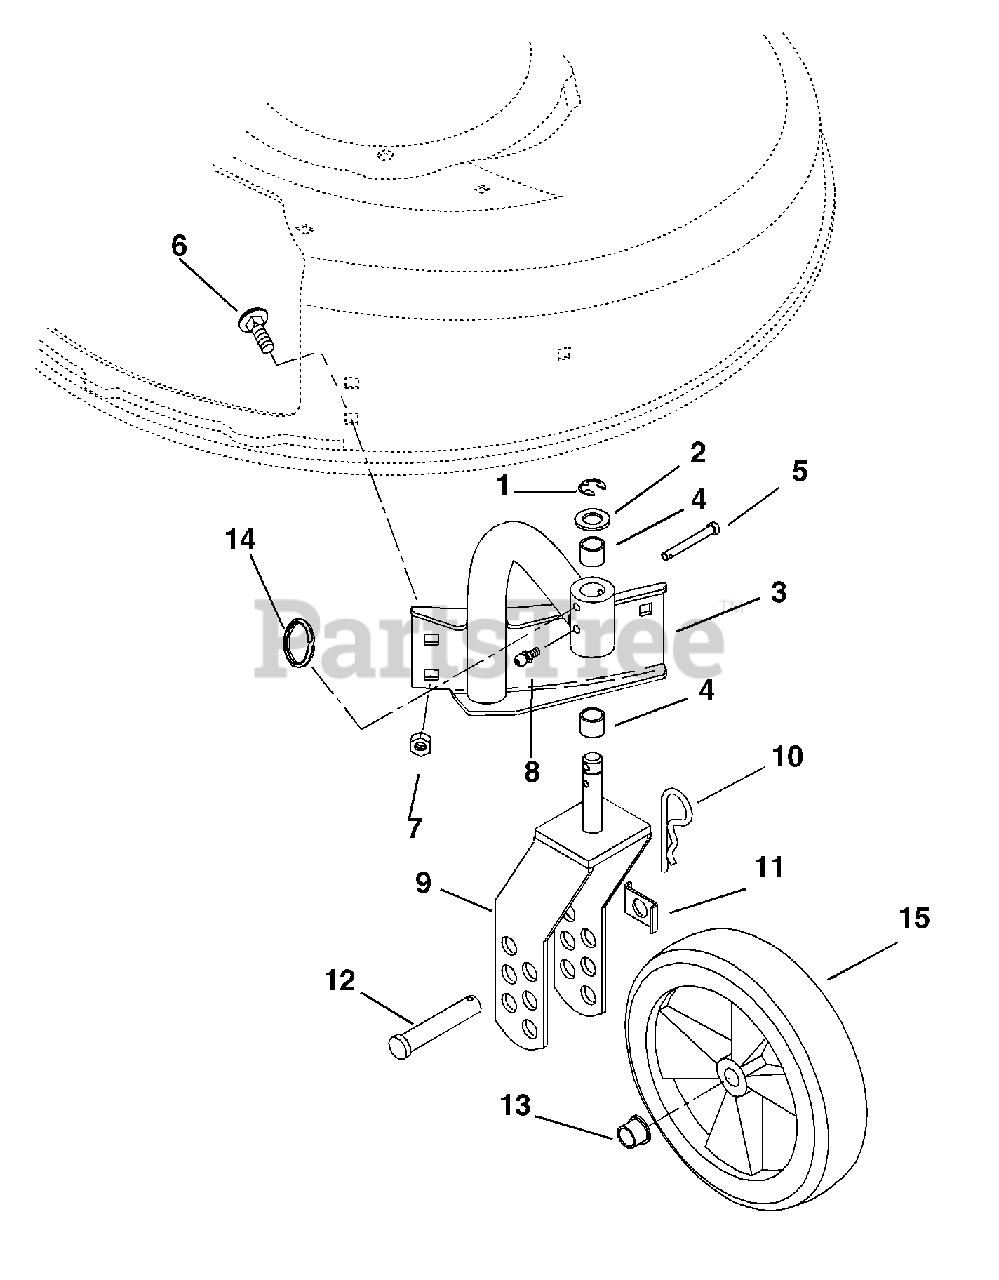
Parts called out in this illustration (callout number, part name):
1	RG-RTNG-EXT .625X.042
2	WSHR-FL-STL .630X1.005X.062 YZ
3	RIGHT MOUNT ARM WELDMENT
4	BSHG-SLV .625X.750X.500 BR
5	PIN-CLEV .25X1.75 YWZC
6	@BLT-RDHDSQNK .31-18X.50 G5YZ
7	@NUT-SPNLK-FLG .312-18 YWZC
8	FTG-LUBE .25-28X.256 YWZC
9	WHEEL YOKE WELDMENT
10	PIN-HAIR-EXT .12X.31X2.37 YWZC
11	AXLE TAB
12	PIN-CLEV .494X2.62 YWZC
13	BSHG-FLG .500X.625X.500X.750
14	KICKOUT RING YWZC
15	WHL 7.50" .50 BORE, 1.50 HUB
